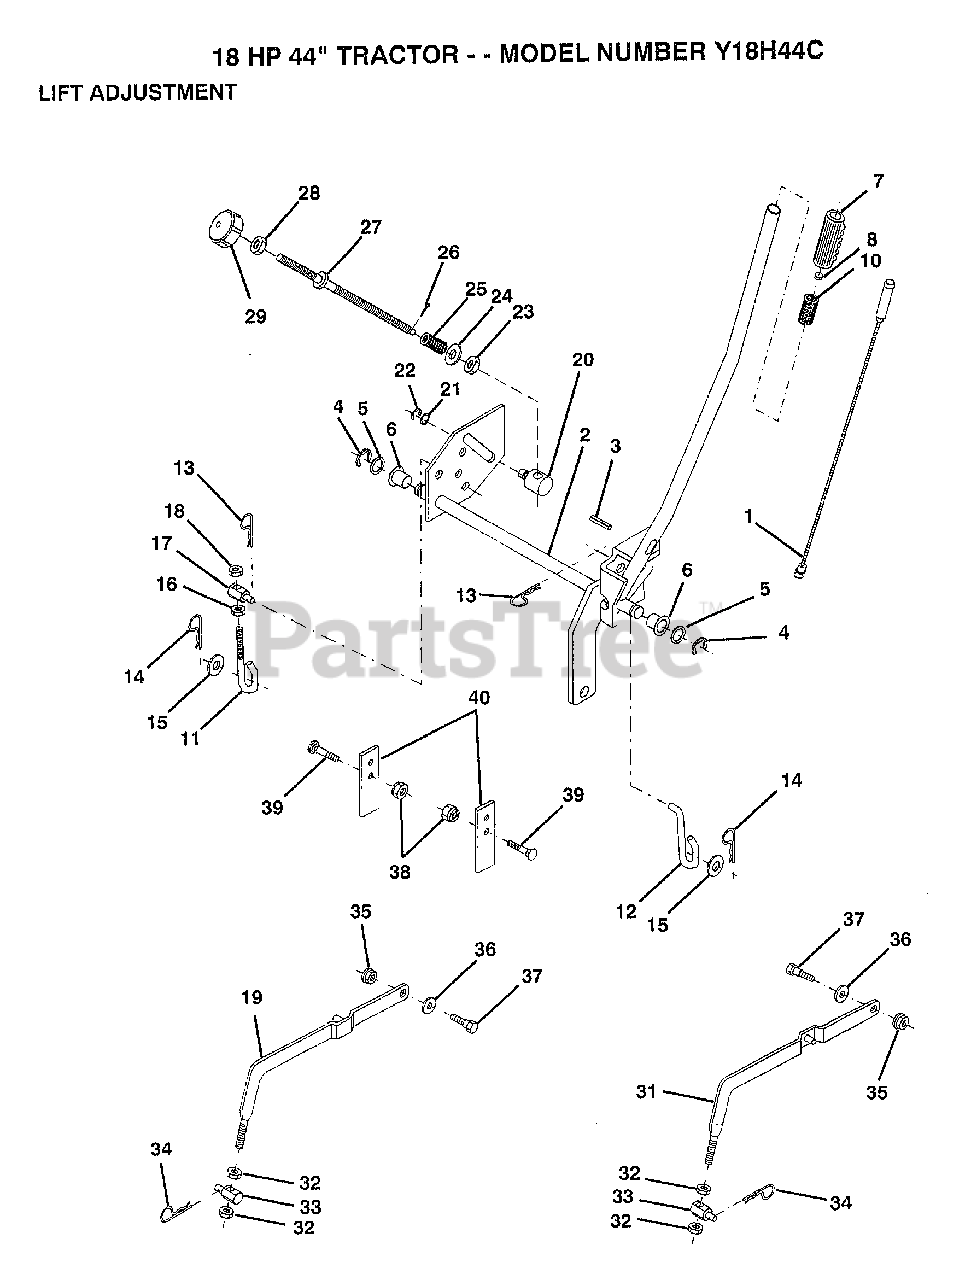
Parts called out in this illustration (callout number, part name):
1	WIRE.ASM.INNER
2	SHAFT.ASM.LIFT.RH
3	PIN GROOVE
5	WASHER
6	NYLON BEARING
7	GRIP
11	PIVOT PIN T
12	LIFT LINK LT
14	SPRING.RETAINER
16	NUT
19	LH SUSP ARM ASM
20	TRUNION LT
21	WASHER
22	KLIP RING
23	NUT T
24	WASHER
25	SPRING T
27	ROD LIFT LT
28	NUT
29	KNOB INF 3/8-16
31	RH SUSP ARM ASM
32	NUT
34	SPRING H
35	NUT SPECIAL T
36	WASHER T
37	"BOLT, SHOULDER LT"
40	UPSTOP
